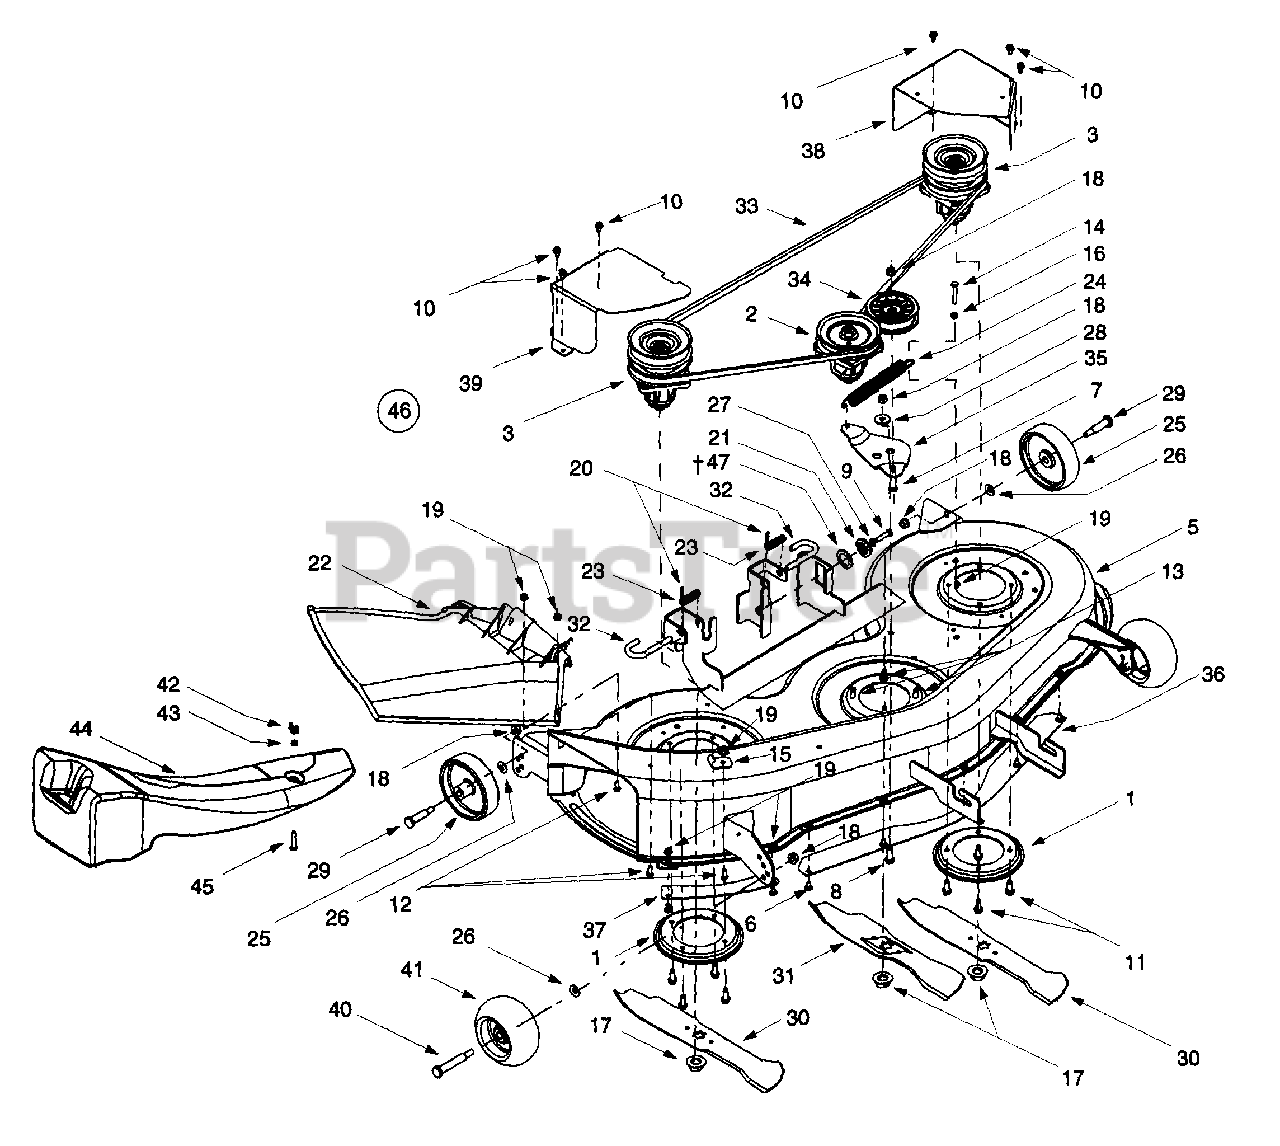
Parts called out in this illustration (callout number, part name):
3	Double Pulley Spindle Assembly
7	Hex Cap Screw, 3/8-16 x 1.75
8	Hex Cap Screw, 3/8-16 x 1.0
9	Hex Cap Screw, 5/16-18 x 1.25
10	Self Tapping Screw, 1/4-20 x .5
11	Self Tapping Screw, 5/16-18 x .875
12	Hex Cap Screw, 1/4-20 x .62
13	Self Tapping Screw, 5/16-18 x .75
14	Hex Cap Screw, 1/4-20 x 1.25 (Grade 5)
15	Retainer Hook
16	Center Lock Nut, 1/4-20
17	Hex Flange Nut, 5/8-18
18	Flange Lock Nut, 3/8-16
19	Hex Flange Lock Nut, 1/4-20
20	Internal Cotter Pin, .072 x 1.12
21	Deck Adjustment Gear
22	Side Discharge Chute Assembly
23	Compression Spring, .406 x .531 x 1.75
24	Extension Spring, .91 x 7.33
25	Deck Wheel, 5 x 1.38
26	Bell Washer, .401 x .87 x .063
27	Lock Washer, 5/16
28	Shoulder Spacer, .625 x .169
29	Shoulder Spacer, .498 x 1.53
30	Three-in-one Blade, Star Center, 16.28
31	Three-in-one Blade, Star Center, 14.88
32	Deck Release Pin
33	Deck Belt
34	Flat Idler Pulley, 3.5 OD
41	Deck Wheel, 5
42	Wing Nut, 1/4-20
43	Center Lock Nut, 1/4-20
44	Mulch Plug
45	Screw, 1/4-20 x 1.5
